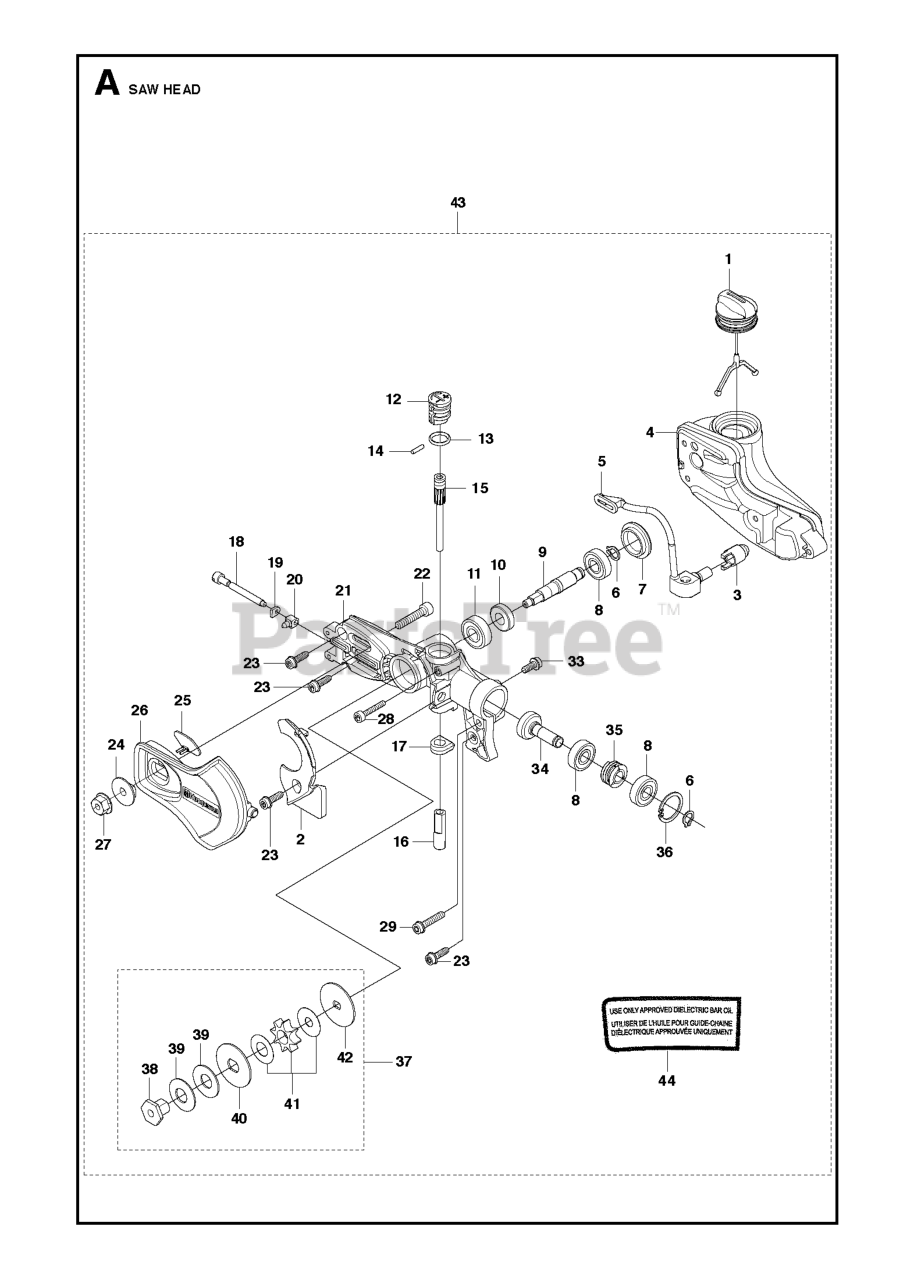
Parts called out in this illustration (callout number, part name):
3	OIL SCREEN
6	RETAINING RING
8	BALL BEARING
10	GEAR WHEEL
11	BALL BEARING
14	NEEDLE ROLLER
15	PISTON PUMP
16	PUMP CYLINDER
21	GEAR HOUSING
22	SCREW IHSCM
27	HEXAGON NUT FLANGED
28	SCREW ITXSCM
33	SCREW
36	RETAINING RING
37	SPROCKET KIT 3/8"
39	DISC SPRING
41	SPROCKET KIT 3/8"
42	WASHER
43	CUTTING HEADS
